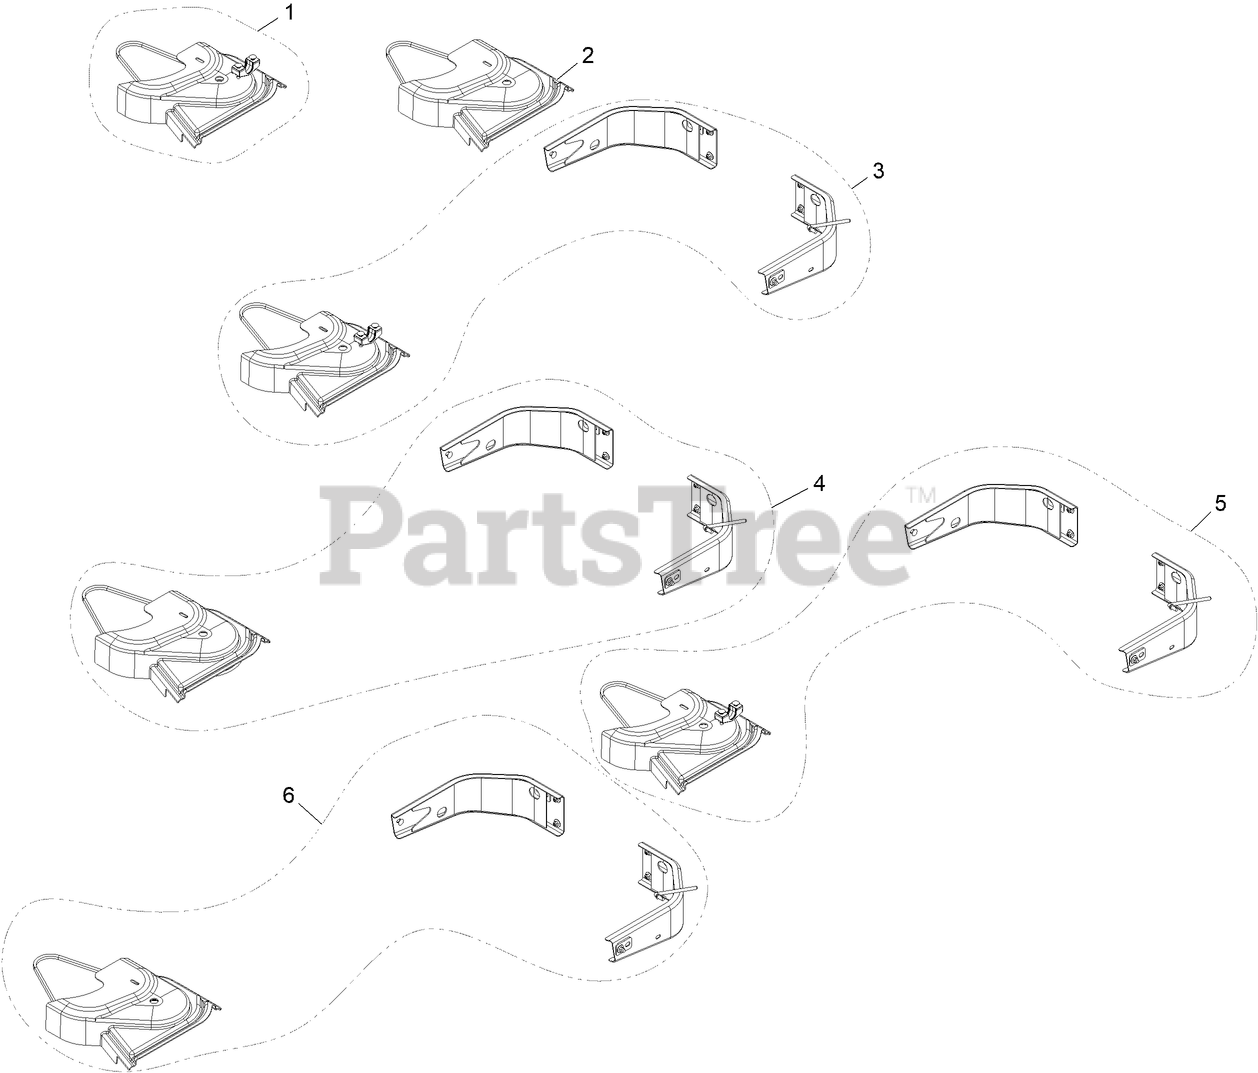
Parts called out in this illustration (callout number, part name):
3	Kit,Uv Drive 604 Splined
4	Kit,Uv Drive 724 Splined
5	Kit,Uv Drive 606
6	Kit,Uv Drive 726
